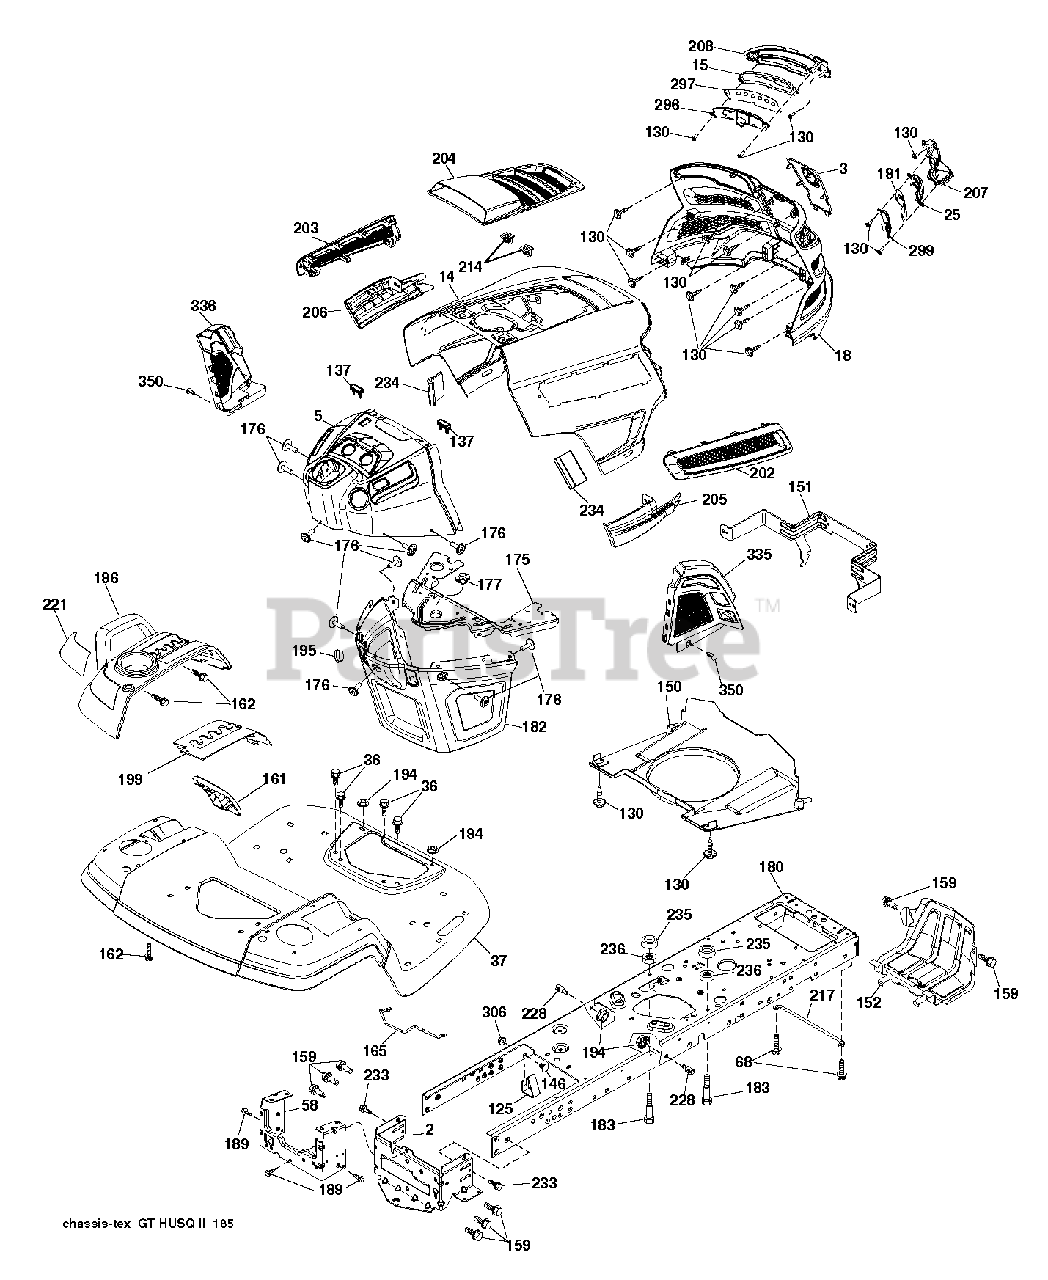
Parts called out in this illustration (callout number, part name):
2	DRAWBAR.LOWER.2PC.18/22
3	APPLIQUE.SUBASM.GT.HUSQ.II
5	DASH
14	HOOD.ASM.HUSQVARNA.GT.TEX.ORAN
15	LED LIGHT.LH
18	GRILLE SUBASM.GT.II.LOW.HDLGHT
25	LENS.RH
36	SCREW 5/16"
37	FENDER.PNT.TX.GT.CH/FW/DL.HUSQ
58	DRAWBAR.UPPER.2PC,LRG.FENDER
68	SCREW LT
125	CLIP.FUEL.LINE
130	SCREW.#10 X 0.750.BOS
137	BUMPER DASH
146	BOLT.RDHD.SHT.SQNK.3/8-16X5/8
150	AIR DUCT.GTV2(1.66"RING HEIGHT
151	BRACKET.PIVOT.HOOD.GT.HUSQ.II
152	SHIELD.BROWNING.PNT.GT.V2
159	SCREW, 3/8-16X3/4
161	CONSOLE.WINDOW.FUEL.HUSQ.GT
162	SCREW.HI-LO.CONSOLE
165	SUPPORT.TANK.REAR.B/TE
175	PLATE.CROSSMEMBER.HUSQ
176	SCREW.#10-24X5/8.RN.QU
177	BUSHING STEERING
180	CHASSIS.TEX.BOLTED
182	DASH.LOWER.COMMON.12V.ADAPTOR
183	BOLT.5/16-18X1-1/4 FULL THD
189	SCREW
191	INSERT INFLECT.RH
194	NUT LOCK HEX FLANGE 5/16-18
195	PLUG.HOLE.DASH.LOWER.12V.BLK
196	SUBASM.CONSOLE.HUSQ.GT.DECKLFT
199	PLATE.DECK.LIFT.HUSQVARNA.GT
202	VENT.SIDE.RH.GT.HUSQ.II.
203	VENT.SIDE.LH.GT.HUSQ.II.498
204	VENT.TOP.ASM.HUSQ.GT2
205	SIDE.TRIM.RH.GT.HUSQ.II
206	SIDE.TRIM.LH.GT.HUSQ.II.GRAY
207	BEZEL GT2 LED RH W/ LOWER.ATT
208	BEZEL GT2 LED LH W/ LOWER ATT
214	CLIP.RETAINER.TINNER.
217	ROD.PIVOT.HOOD
221	REFLECTOR.LH.TEX GT HU
228	STUD.FASTNER.W/ANTI-ROTATE
233	BOLT.SHOULDER
234	BUMPER.HOOD.TEX.HUSQVARNA
235	SPACER FENDER
236	NUT.CENTERLOCK.5/16-
296	LED LIGHT.LH
297	INSERT REFECT LH
299	LED LIGHT.RH
306	NUT LOCK FLG 3/8-16 UNC
335	COVER.LOWER.DASH.RH.BLACK
336	COVER-LH.LOWER.DASH.GT2.BLACK
350	CLIP.X-MAS.TREE
